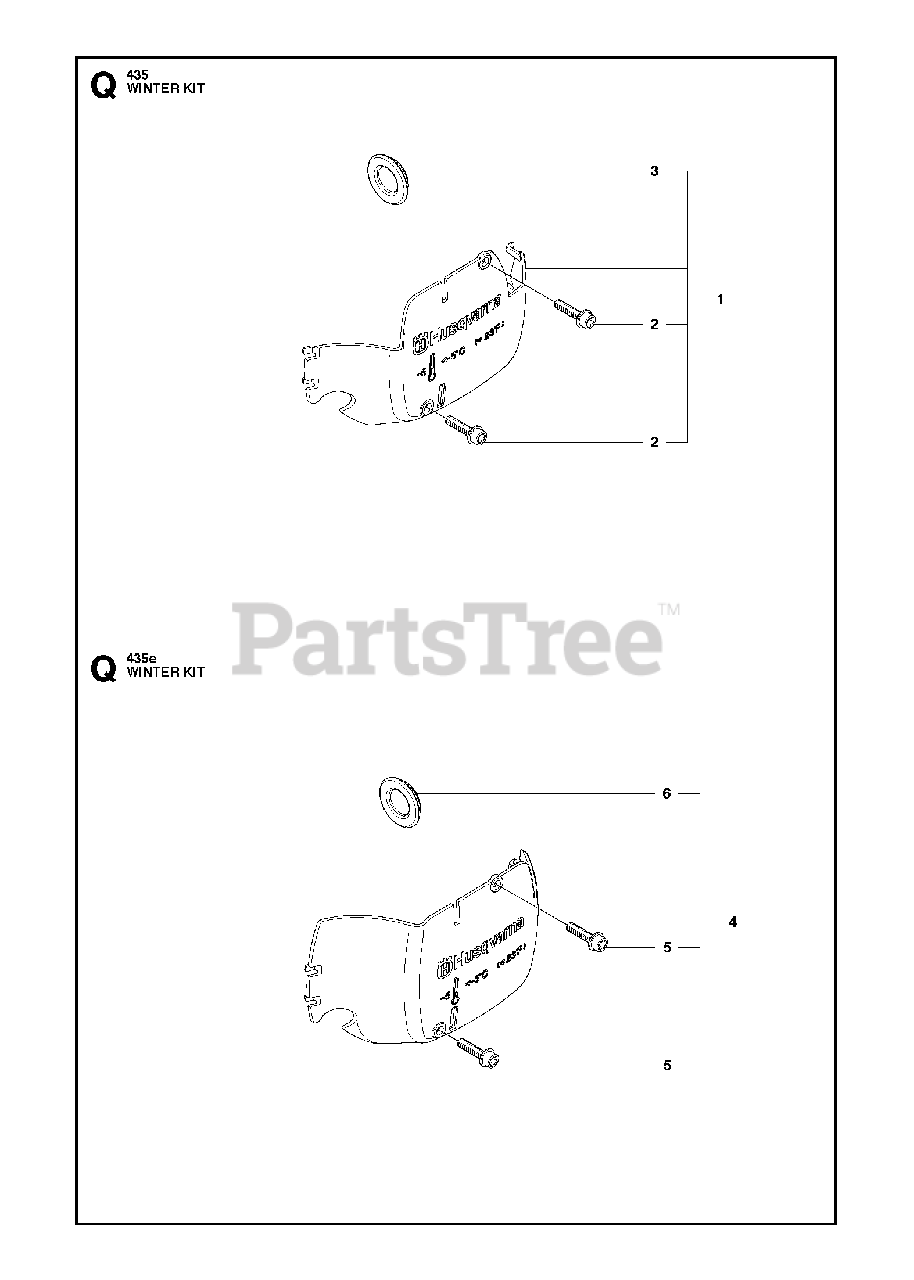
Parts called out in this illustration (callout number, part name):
1	WINTER KIT
2	SCREW
3	PLUG
4	WINTER KIT
5	SCREW
6	PLUG
